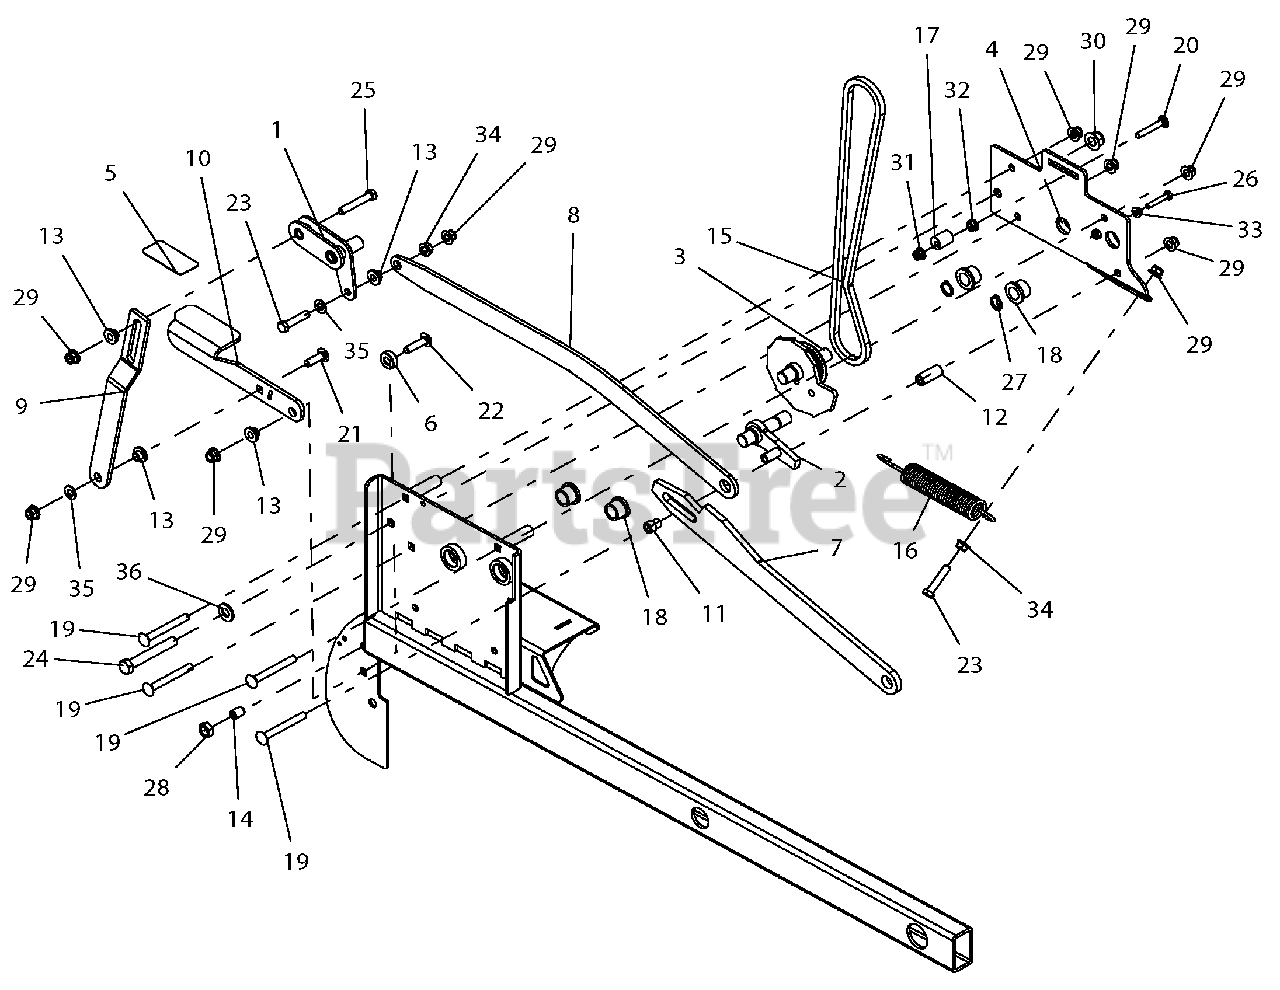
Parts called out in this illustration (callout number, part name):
1	WLDMT, REAR PEDAL PIVOT
2	WLDMT, TRAILER LOCK
3	WLDMT, HOC CAM
4	WLDMT, CAM COVER
5	GRIP, PEDAL 1.50 X 3.00
6	SPCR, .375 X 1.00 X .342
7	ARM, CAM CONTACT
8	ARM, PEDAL
9	ARM, PEDAL
10	PEDAL, DECK LIFT FOOT-BLACK
11	BSHG, FLG .385 X .500 X .812 X .437
12	SPCR, .385 X .625 X 1.438
13	BSHG, FLG .385 X .500 X .875 X .406
14	BALL SPRING PLUNGER, .500-13
15	BELT, 5MM HTD
16	SPRG, TENSION .162 X 1.250 X 8.250
17	ECCENTRIC
18	BUSHING, .750 X 1.00 X .750
19	BLT-RDHDSQNK .38-16X3.25 G5 Y
20	BLT-RDHDSQNK .31-18X2.0 FTH G5 Y
21	BLT-RHDSSQNK .38-16X1.25 G5YZ
22	BLT-RHDSSQNK .38-16X1.50 G5YZ
23	BLT-HEX .38-16X1.75 GR5 YWZC
24	BLT-HEX .50-13X3.50 GR5 YWZC
25	BLT-HEX .38-16X2.25 GR5 YWZC
26	BLT-HEX .25-20X1.50 GR5 YWZC
27	RG-RTNG-EXT .750x.078
28	NUT, JAM .500-13 YWZC
29	NUT-LK-NYL-FLG .38-16 YWZC
30	NUT-LK-NYL-FLG .50-13 YWZC
31	NUT-LK-NYL-FLG .31-18 YWZC
32	@NUT-SPNLK-FLG .312-18 YWZC
33	@NUT-SPNLK-FLG .25-20 YWZC
34	@NUT-SPNLK-FLG .375-16 YWZC
35	WSHR-FL-STL.406X.812X.065 YWZ
36	WSHR-FL-STL.531X1.06X.095YWZC
